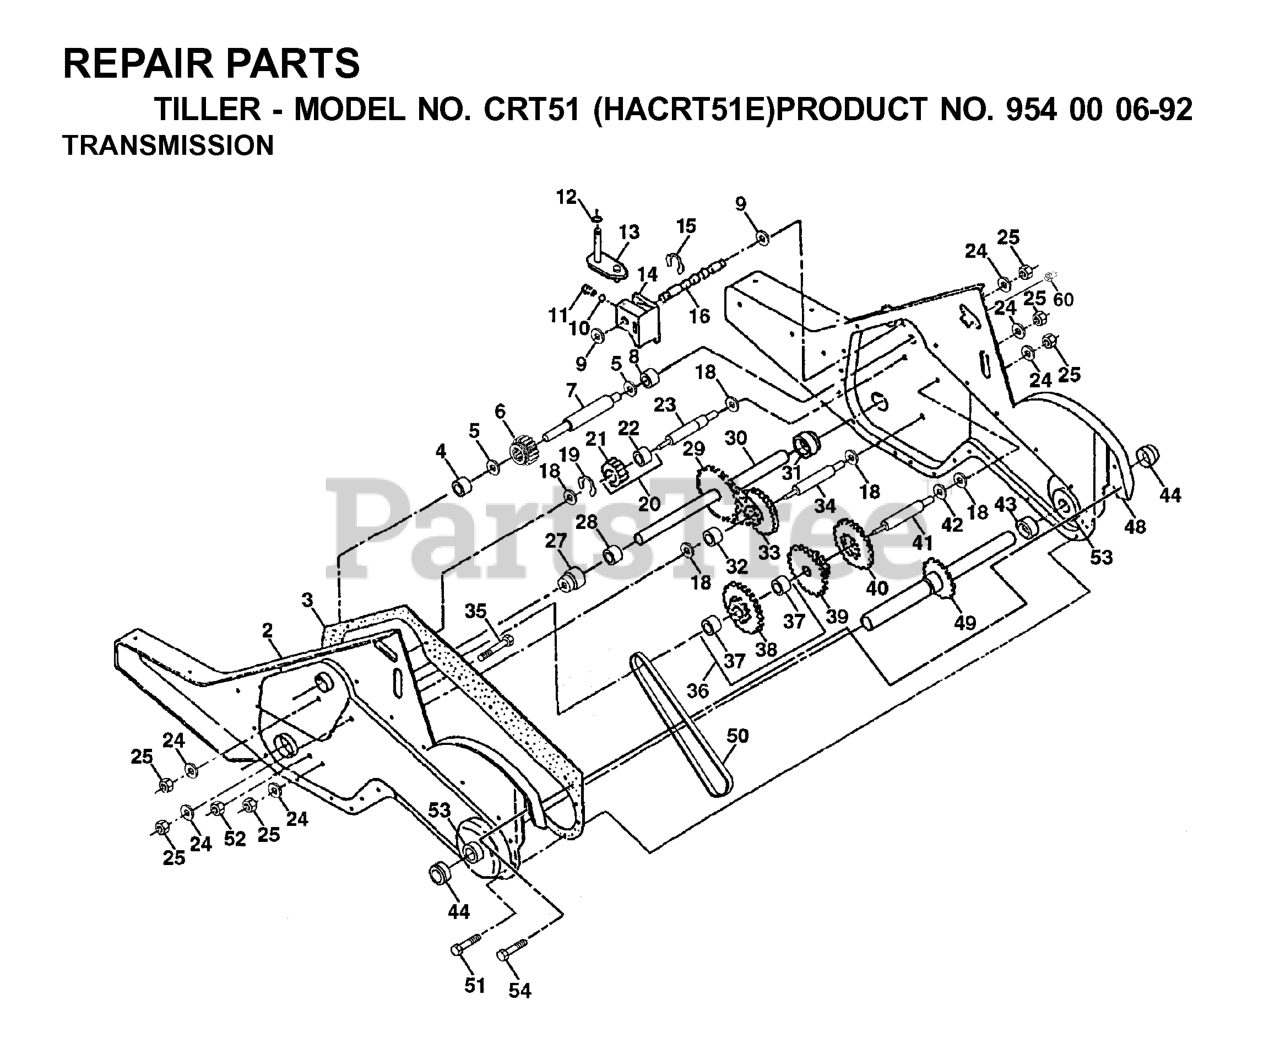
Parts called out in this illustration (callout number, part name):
1	TRANSMISSION ASSY
2	GEARCASE-LH
3	GASKET
4	NEEDLE BRNG LT
5	THRUST WASHER
6	GEAR.PINION.INPUT
7	SHAFT.INPUT."D".TILLER
8	BEARING TI
9	WASHER, SEAL (2 2)
10	STEEL BALL KIT
11	SPRING-SHIFT CRT
13	BRACKET ASM.SHIFT.CRT
14	SHIFT FORK TI
16	SHAFT.SHIFTER.TILLER
20	GEAR ASSY CRT
21	GEAR-REV IDLR CRT
22	NEEDLE BEARING TI
24	LOCKWASHER
25	NUT.ASF.HEX.7/16
27	BEARING, SHAFT LH CRT
30	GROUND SHAFT ASS'Y
31	BEARING, SHAFT RH CRT
33	SPRCKT 8 GEAR CRT
34	SHAFT.SECONDARY.REDUCTION.CRT
35	SCRW WHIZ LOK CRT
36	SPROCKET.ASM.W/BEARING.TILLER
37	BEARING
38	SPROCKET, TINE
41	SHAFT.REDUCTION.TILLER
42	BRNG RACE T
44	SEAL ASM, OIL
48	GEARCASE
49	TINE SHAFT
50	CHAIN.TILLER
51	SCREW
53	KIT.BEARING.TILLER.
54	SCREW 1/4-20X3/4
60	ZERK M
